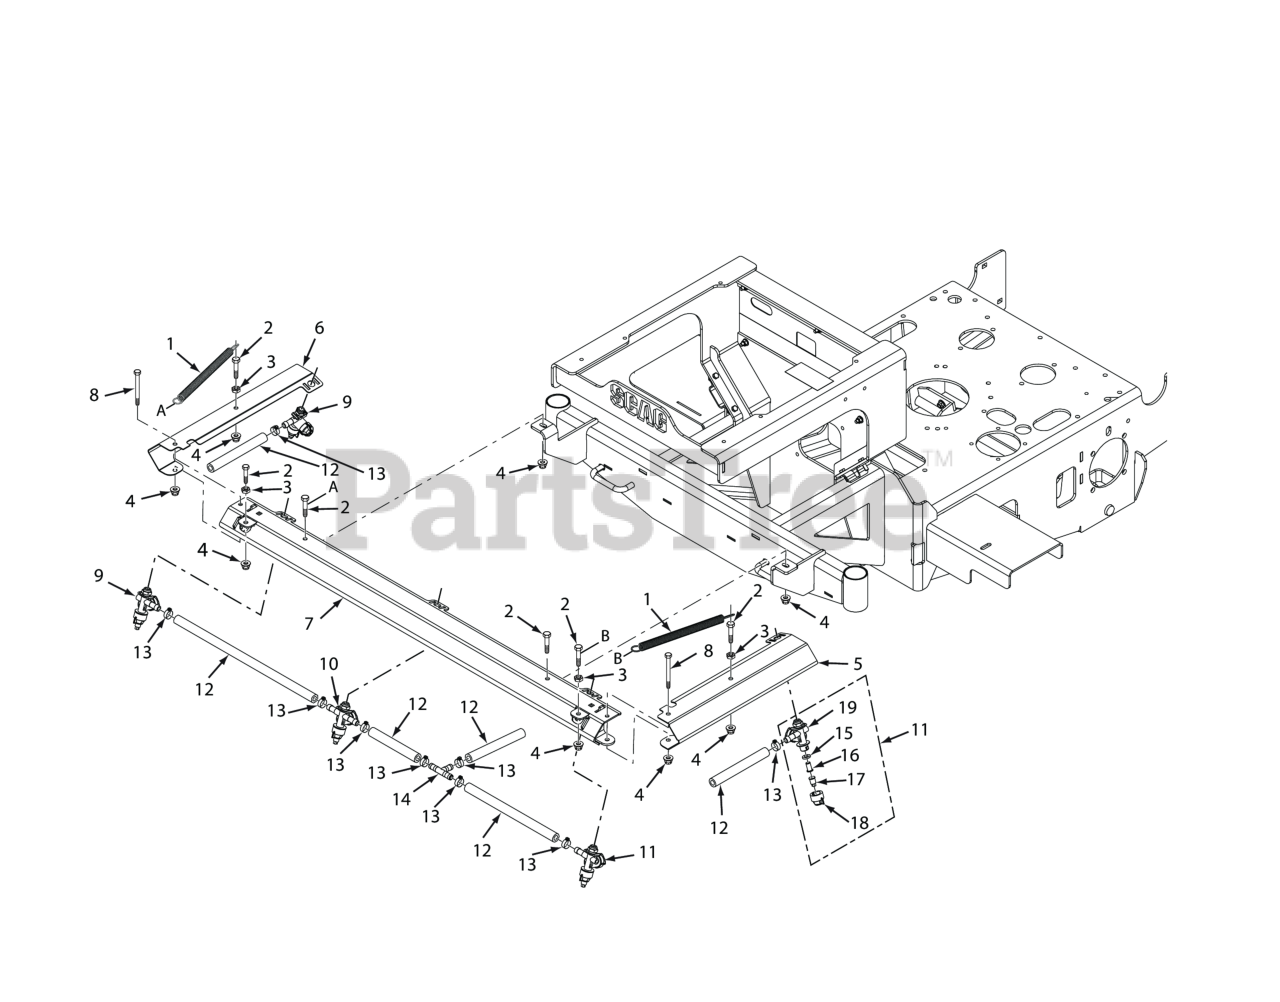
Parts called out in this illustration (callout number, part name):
1	Spring, Boom Arm
2	Bolt, Hex Head 3/8 - 16 x 1.50 - Stainless Steel
3	Nut, 3/8 - 16 - Stainless Steel
4	Nut, Flange Elastic Stop 3/8 - 16 - Stainless Steel
5	Boom, LH
6	Boom, RH
7	Boom, Main
8	Bolt, Hex Head 3/8- 16 x 3.50 - Stainless Steel
9	Nozzle Assembly, RH
10	Nozzle Assembly, Main
11	Nozzle Assembly, LH
12	Hose, 1/2" EPDM (order by the inch)
13	Clamp, Cable 3/4" I.D.
14	Fitting, Tee 1/2" Hose Barb
15	Washer, Rubber
16	Nozzle, Strainer #50 Mesh
17	Nozzle Tip
18	Nozzle Cap
19	Nozzle Body, Single LH (used in #11)
